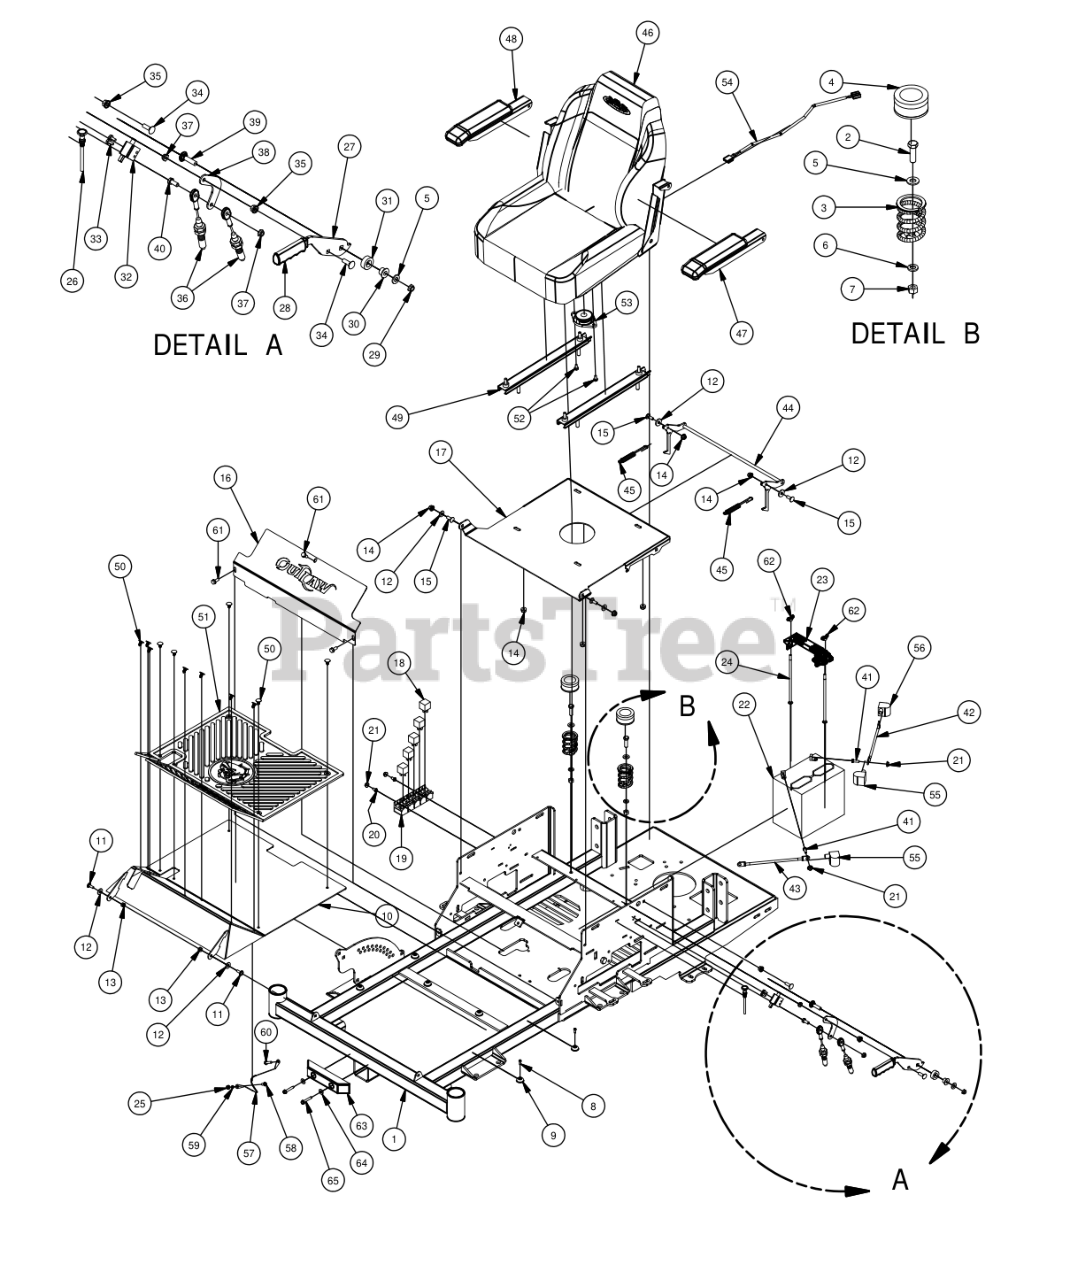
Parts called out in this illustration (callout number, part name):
1	2016 Compact Outlaw Frame
2	3/8" x 1 1/4" Hex Bolt
3	Seat Spring
4	Seat Spring Cap Cover
5	3/8" Flat Washer
6	3/8" Lock Washer
7	3/8-16 Hex Nuts Zinc
8	# 10 x 1/2" Self Taping Screw
9	Button Bumper
10	Compact Outlaw Floorboard
11	1/4" x 3/4" Carriage Bolt
13	1/4 Nylock Nut
14	5/16-18 Nylon Flange Nut
15	5/16" x 7/8" Carriage Bolt
16	Compact Outlaw Cooler Cover
17	Seat Plate 2016
19	Wire Harness
20	1/4" x 1/2" BS C/S 18-8 SS
21	1/4-20 Hex Flange Nuts Zinc w/Serrations
23	Battery Hold Down
24	1/4-20 X 8 Carriage Bolt
25	1/4-20 Hex Nut
27	Brake Handle Cam Over
28	Rubber Brake Grip-cZT/ZT 2013
29	3/8-16 Centerlock Half Nut
30	Bronze Bushing SF-1220-8
31	2015 Brake Lever Spacer
32	Safety Switch
33	12-24x 1/2 HWH Bolt
34	5/16" x 1" Carriage Bolt
35	5/16" Flange Nut w/Serrations
36	Brake Cable
37	5/16-18 Nylock Jam Nut 1/2 Nut
38	Brake Cable Adapter Bracket
39	3/8 x 1 1/2 Carriage Bolt
40	5/16" x 3/4" Hex Bolt
41	1/4" x 3/4" Hex Bolt
42	24" Red Battery Cable
43	Ground Cable
44	Seat Latch Rod Assembly 2016 Models
45	Seat Latch Spring
46	Compact Outlaw Seat
47	Left Arm Rest
48	Right Arm Rest
49	Seat Rails
50	5/8" Christmas Tree Fastener
51	Compact Outlaw Floor Mat
52	1/4-20x1/2 HWH Bolt Slot
53	Seat Safety Switch
54	Seat Switch Adapter
55	Black Boot For Ground Cable
57	Floor board Cable W/ Swivel Ends
58	1/4" x 5/8" BS C/S 18-8 SS
59	1/4" Lock Washer
60	1/4 x 1 Hex Head Tek screw
61	5/16 x 3/4 washer head type F screw
62	1/4" Wing Nut
63	8" Rubber Bumper
64	5/16" Flat Washer
65	1/4" x 1 1/2" Self Tapping Screw
